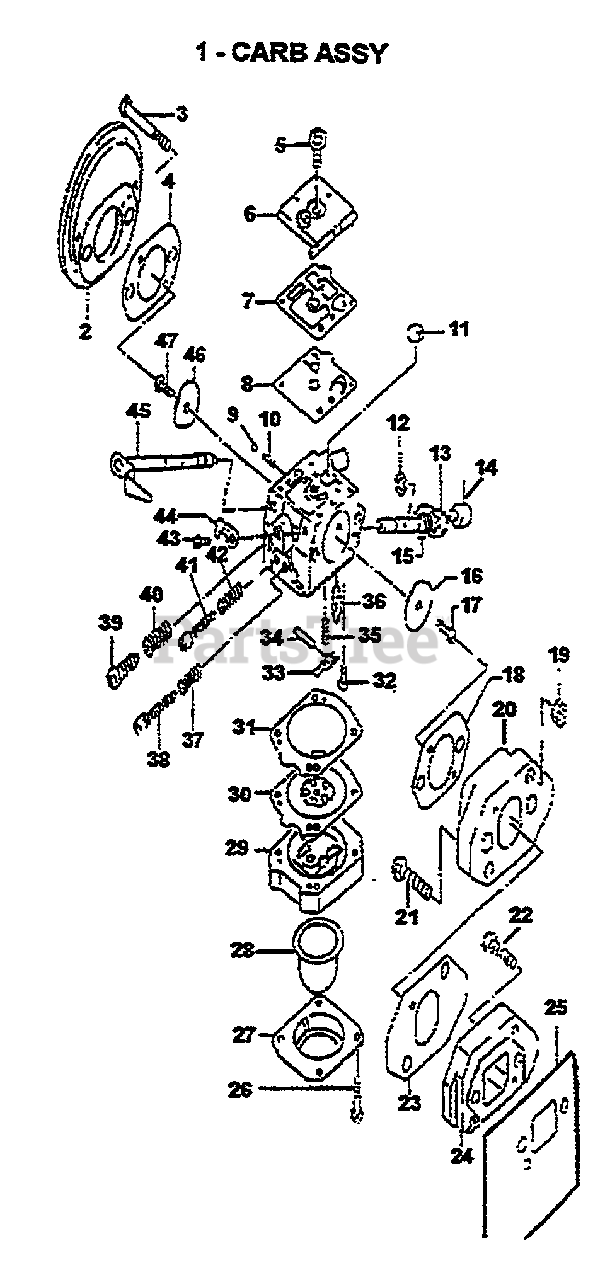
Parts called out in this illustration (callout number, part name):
1	CARB ASSY
6	PUMP COVER
7	GASKET, DIAPHRAGM
8	DIAPHRAGM, PUMP
12	SNAP RING
15	SPRING
16	THROTTLE, VALVE
17	SCREW
20	INSULATOR
23	GASKET
27	COVER
28	PRIMER PUMP
30	DIAPHRAGM
33	ARM, FLOAT
36	VALVE, FLOAT
38	NEEDLE JET
40	SPRING
41	NEEDLE JET
43	SCREW
44	PLATE
45	SHAFT ASSY
46	VALVE, CHOKE
47	SCREW
